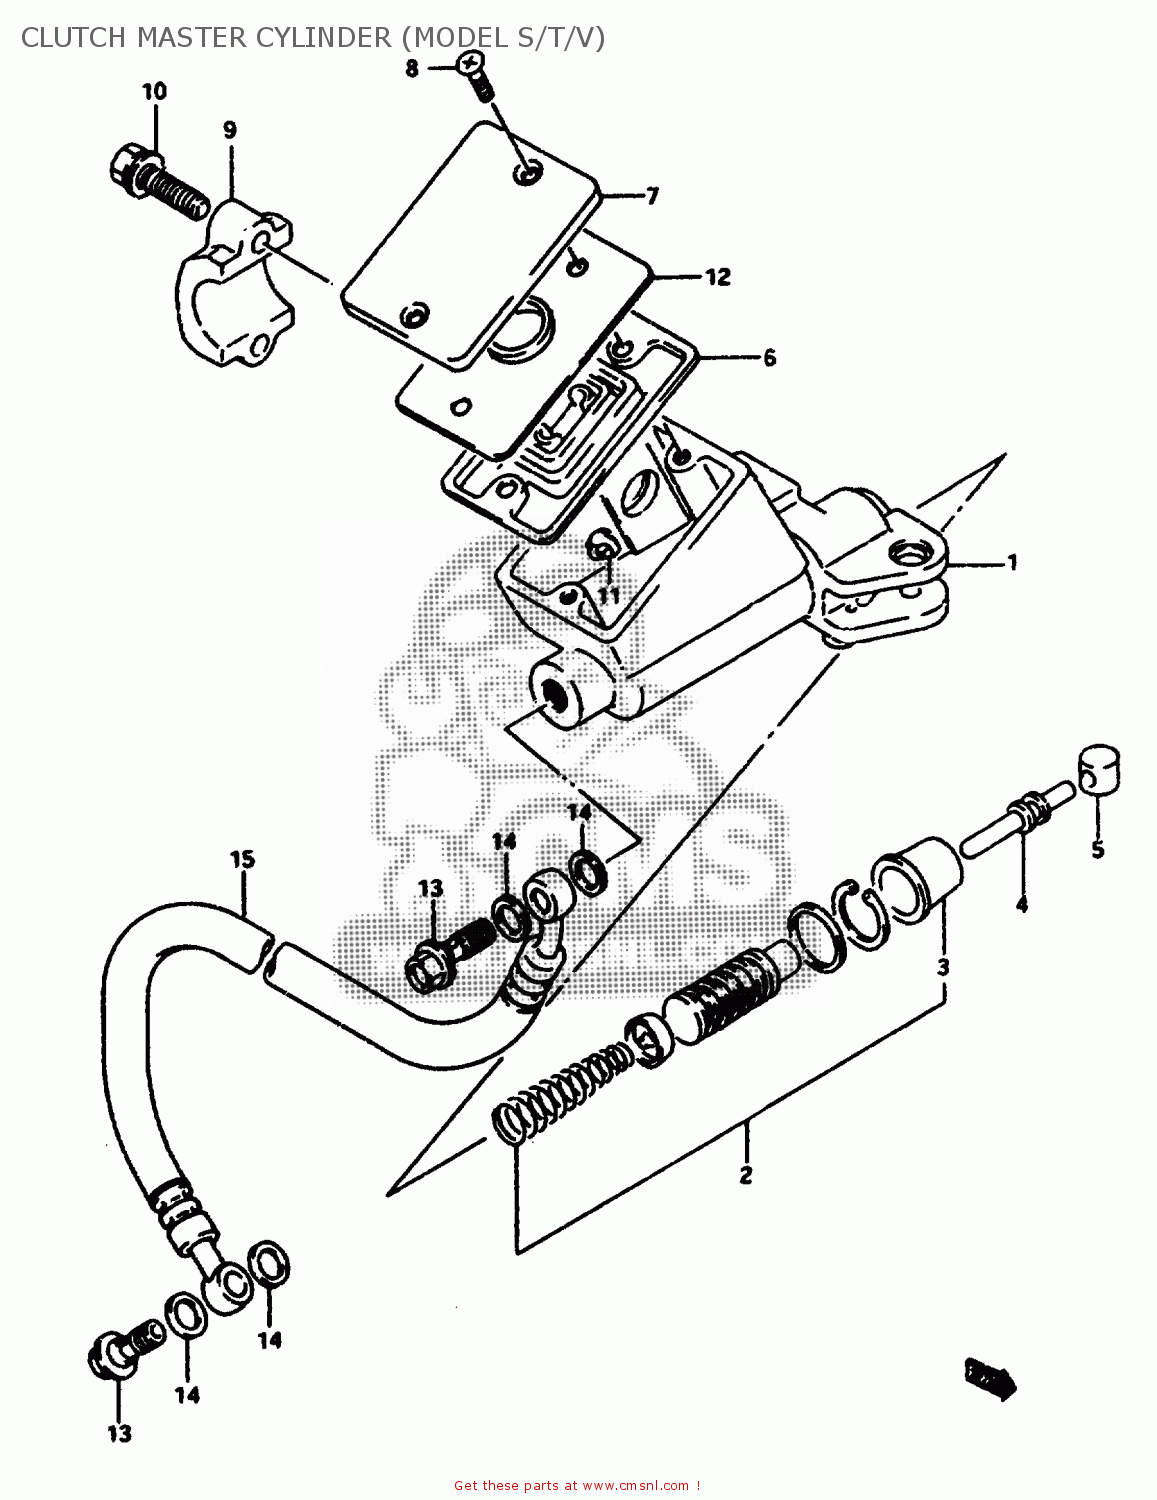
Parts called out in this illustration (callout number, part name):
1	CYLINDER ASSY,CLUTCH MASTER
2	PISTON & CUP SET
3	BOOT
4	ROD,PUSH
5	BUSH
6	7
7	CAP
8	SCREW
9	HOLDER
10	BOLT(6X25)
11	PROTECTOR
12	PLATE,DIAPHRAGM
13	BOLT UNION
14	WASHER(10X15X1.5)
15	HOSE,CLUTCH
